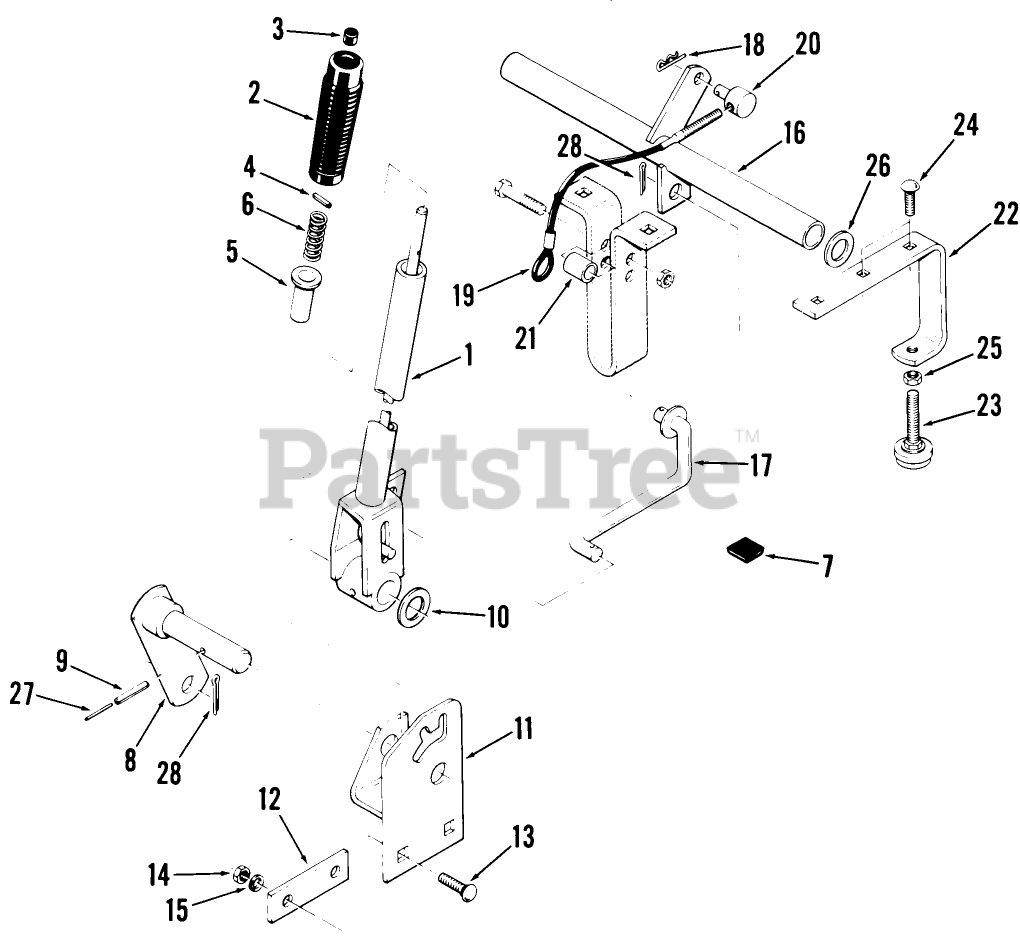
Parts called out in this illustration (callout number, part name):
1	ASSY-HANDLE
2	HANDGRIP
3	CAP-ROD, PLUNGER
4	PIN-SPIROL
5	RETAINER-SPRING
6	SPRING-COMPRESSION
7	BUMPER
8	Lift Arm
9	ROLL PIN 1/4 X 1-1/4
10	RACE
11	ASSY-QUADRANT
12	Spacer
13	Bolt
14	Nut
15	Bolt
16	ASSY-LIFT TUBE
17	ROD-CONNECTING
18	Hairpin Cotter
19	Lift Cable
20	TRUNNION-CLUTCH ROD
21	SPACER
22	BRACKET-BUMPER
23	LEVELER MOWER
24	Bolt-Carriage
25	Nut
26	WASHER
27	PIN-SPIROL
28	Cotter Pin
